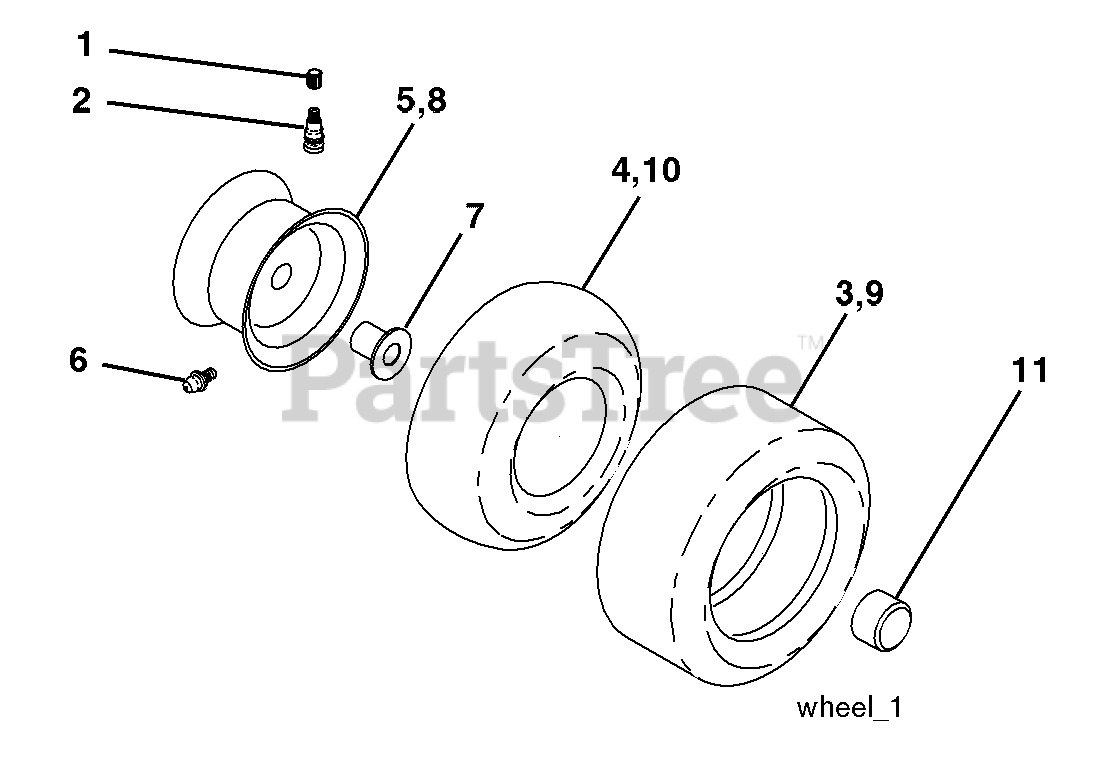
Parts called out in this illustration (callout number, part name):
1	Cap Valve Tire
2	Stem Valve
3	Tire F Ts 15 x 6 0 - 6 Service
4	Tube Front
5	Rim Asm 6"front Silver Service
6	Fitting Grease
7	Bearing Flange
8	Rim Asm 8"rear Silver Service
9	Tire R Ts 20 x 10-8 C Service
10	Tube Rear
11	Cap Axle Blk 1 50 x 1 00
